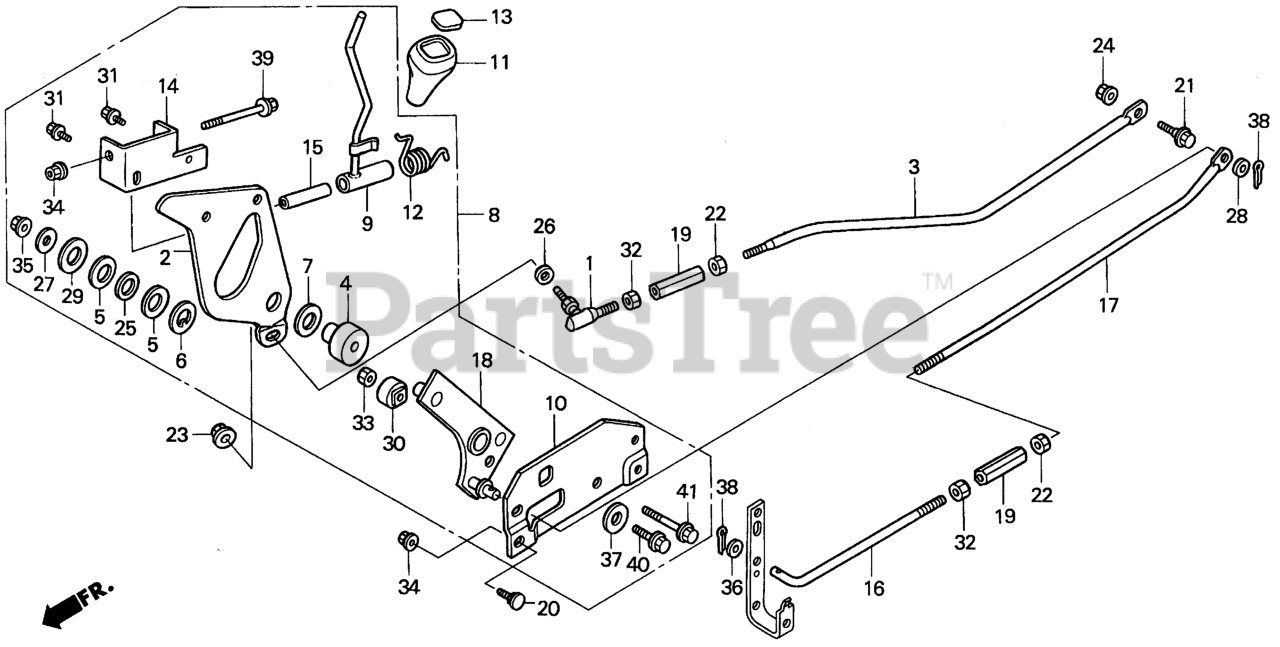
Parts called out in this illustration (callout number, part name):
1	JOINT, R. BALL
2	ARM, CHANGE
3	ROD, GEARSHIFT
4	SHAFT, CHANGE ARM
5	SPRING, FRICTION
6	WASHER, FRICTION SETTING
7	WASHER, FRICTION
8	LEVER ASSY., CHANGE (NOT AVAILABLE)
9	LEVER, CHANGE
10	HOLDER, CHANGE LEVER (NOT AVAILABLE)
11	GRIP, CHANGE LEVER
12	SPRING, CHANGE LEVER
13	KNOB, CHANGE LEVER GRIP
14	BRACKET, CHANGE LEVER
15	COLLAR, CHANGE LEVER JOINT
16	ROD, RETURN (A)
17	ROD, RETURN (B)
18	ARM A, RETURN
19	JOINT (12MM)
20	BOLT, SPECIAL (8X20)
21	BOLT, ADJUSTING CENTER
22	NUT, L. HEX. (12MM)
23	NUT, FLANGE (5/16-24UNF)
24	NUT, FLANGE (8MM)
25	WASHER, THRUST (26MM)
26	WASHER, HEAD (8MM)
27	WASHER (12.5X33)
28	WASHER (13X20)
29	WASHER, SPRING SETTING
30	BUSH (12.1X23X20)
31	BOLT-WASHER (8X16)
32	NUT, HEX. (12MM)
33	NUT, HEX. (12MM)
34	NUT, FLANGE (8MM)
35	NUT, FLANGE (12MM)
36	WASHER, PLAIN (12MM)
37	WASHER, PLAIN (12MM)
38	PIN, SPLIT (3.0X25)
38	PIN, COTTER (3.0X45)
39	BOLT, FLANGE (8X80)
40	BOLT, FLANGE (12X25)
41	BOLT, FLANGE (12X60)
